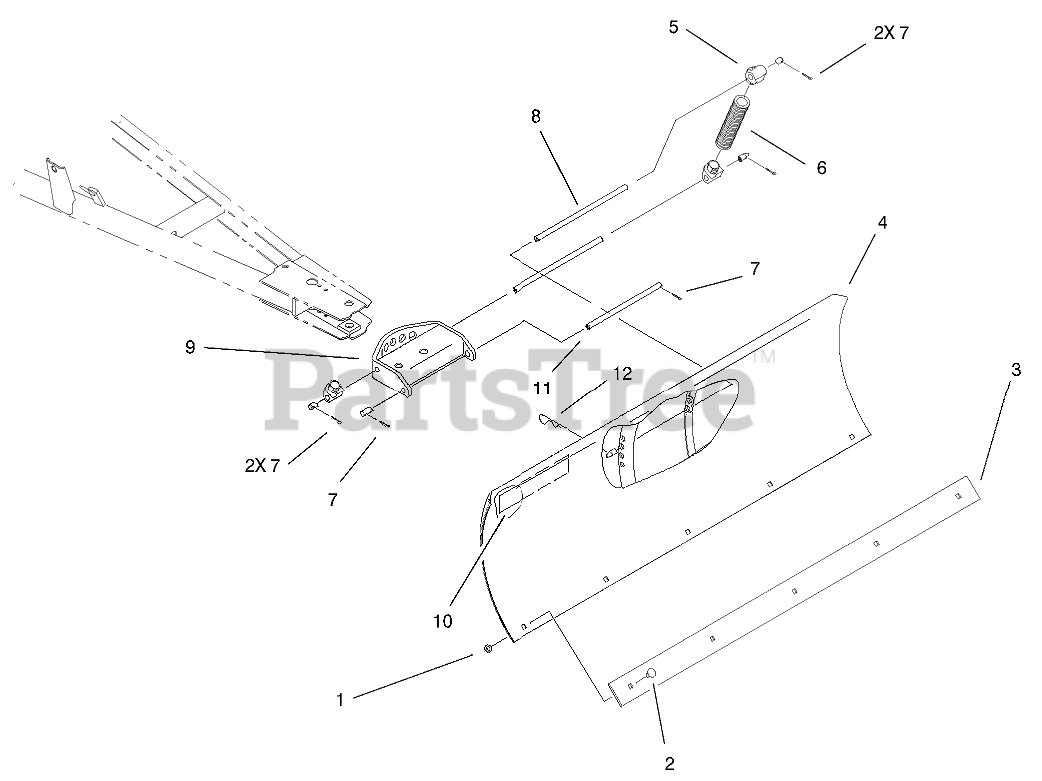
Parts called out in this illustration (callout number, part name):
1	NUT-LOCK, NI
2	SCREW-CARR
3	PLATE - BLADE EDGE
4	BLADE ASM
5	Lug-Spring
6	Spring-Trip Return
7	PIN-COTTER
8	ROD-PIVOT, BLADE
9	QUADRANT
10	DECAL-ATTACHMENT
11	ROD-LOWER
12	PIN-HAIR
